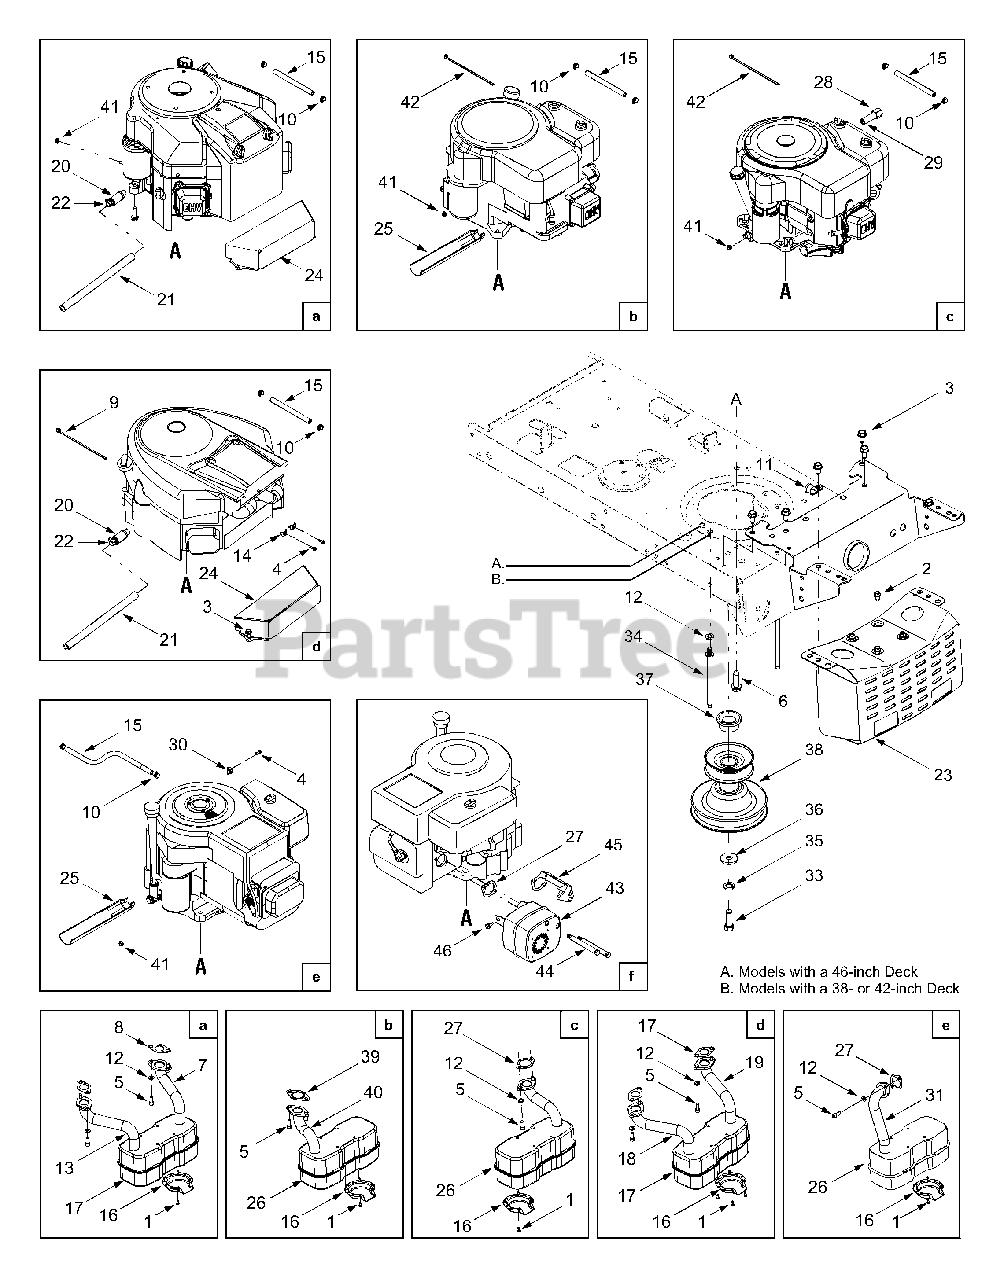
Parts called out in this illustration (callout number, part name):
1	Screw, #8-32 x .375
2	Self-tapping Screw, 1/4-20 x .5
3	Self-tapping Screw, 5/16-12 x .75
4	Screw, #10-32 x .625
5	Socket Cap Screw, 5/16-18 x .625
6	Self-tapping Screw, 3/8-16 x 1.25
7	LH Exhaust Pipe
8	Exhaust Gasket
9	Push-mount Cable Tie, 7.5
10	Hose Clamp, .490
11	Clamp, 9/16
12	Lock Washer, 5/16
13	RH Exhaust Pipe
14	Casing Clamp
15	Fuel Line Hose
16	Muffler Deflector
17	Muffler, Twin Inlet
18	RH Exhaust Pipe
19	LH Exhaust Pipe
20	Oil Drain Valve
21	Oil Drain Hose
22	Oil Drain Cap
24	Engine Heat Shield
25	Oil Drain Sleeve
26	Muffer, Single Inlet
27	Exhaust Gasket
28	Oil Drain Cap, 3/8-18
29	Oil Drain Pipe, 3/8-16 x 2.0
30	Casing Clamp
31	Exhaust Pipe
33	Hex Screw, 7/16-20 x 1.25
34	Belt Keeper Pin, 5/16 x 4.75
35	Lock Washer, 7/16
36	Flat Washer, .450 x 1.25 x .164
37	Spacer, 1.0 x 1.4 x .825
38	Engine Pulley, 3.12 x 5.56
39	Exhaust Gasket
40	Exhaust Pipe
41	Hex Sems Nut, 1/4-20
42	Cable Tie, 7.4"
43	Square Muffler
44	Shoulder Screw, .43 x 3.57
45	Shield
46	Self-tapping Screw, 1/4-20 x .63
